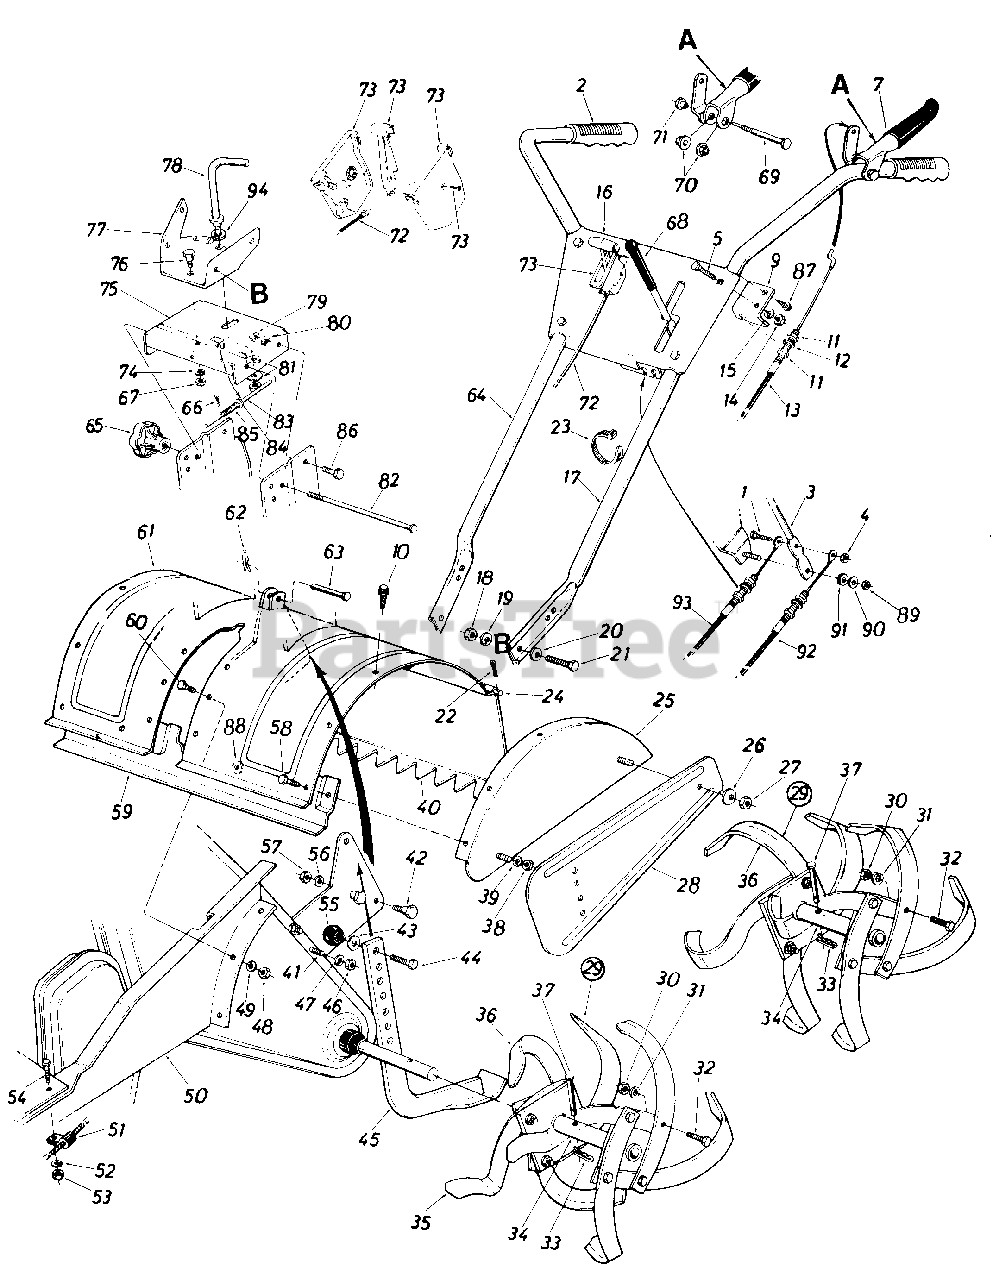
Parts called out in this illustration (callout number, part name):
1	Hex Bolt 1/4-28 x 1.0" Lg.*
2	Grip
3	Clutch Lever
4	Hex Cent. L-Nut 1/4-28 Thd.
5	Carr. Bolt 5/16-18 x 1.75"*
7	Clutch Grip Ass'y.-L.H.
9	Clutch Cable Bracket
10	Hex Wash. S-Tap Scr. 5/16-18 x .62" Lg.
11	Hex Nut 5/16-24 Thd.
12	L-Wash. 5/16" I.D.*
13	Clutch Control Cable
14	Hex Nut 5/16-18 Thd.*
15	L-Wash. 5/16" I.D.*
16	Handle Panel Ass'y.
17	Handle Panel Ass'y.
18	Handle-L.H.
19	Hex Nut 3/8-16 Thd.*
20	Bell-Wash. 3/8" I.D.
21	Hex Bolt 3/8-16 x 1.00" Lg.*
22	Cotter Pin 3132" Dia. x 314"*
23	Cable Tie
24	Tiller Flap Rod
27	Hex Nut 5/16-18 Thd.*
30	Hex Nut 3/8-24 Thd.*
31	L-Wash. 3/8" I.D.*
32	Hex Bolt 3/8-24 x 1.25" Lg.*
33	Hairpin Cotter
38	Hex Nut 5/16-18 Thd.*
39	L-Wash. 5/16" I.D.*
41	Hex Bolt 5/16-18 x 1.0" Lg.*
42	Shld. Bolt 1/2" Dia. x .42611
43	Fl-Wash. 3/8" I.D. x 518" O.D.
44	Hex Bolt 3/8-16 x 314" Lg.*
46	Hex Nut 5/16-18 Thd.*
47	L-Wash. 5/16" I.D.*
48	Hex Nut 5/16-18 Thd.
49	L-Wash. 5/16" I.D.
52	L-Wash. 5/16" I.D.
53	Hex Nut 5/16-18 Thd.
54	Hex Bolt 5/16-18 x 3/4" Lg.
55	Ball Knob 11/4" Dia.
56	L-Wash. 3/8" I.D.
57	Hex Nut 3/8-16 Thd.
58	Hex Bolt 5/16-18 x .75" Lg.
60	Hex Bolt 5/16-18 x .75" Lg.
62	Hairpin Cotter
63	Clevis Pin 3/8" Dia.
64	Handle-R.H.
65	Hand Knob
66	Cotter Pin 1/16" Dia. x .75
67	Hex Cent. L-Nut 3/8-16 Thd.
69	Shoulder Bolt .375" Dia. x 1.37" Lg.
70	Hex Flange Plastic Bearing
71	Shoulder Nut 1/4-20 Thd.
72	Throttle Control Wire
73	Throttle Control Box Ass'y.
74	Bell-Wash. .40" I.D. x 1.13"
79	Hex Cent. L-Nut 3/8-16 Thd.
80	Bell-Wash. .40" I.D. x .88"
81	Bell-Wash. 1/2" I.D. x 1.00"
82	Lock Pin 5/16" Dia. x 8"
83	Lower Sliding Ass'y.
84	Fl-Wash. .291" I.D. x .62"
85	Compression Spring .36" O.D. x 1.00" Lg.
86	Shoulder Bolt 1/2" Dia. x . 170" Lg.
87	Hex Wash. S-Tap Scr. 1/4-20 x.50" Lg.
88	Bell-Wash. 5/16" I.D.
89	Hex Cent. L-Nut 5/16-18 Thd.
90	Fl-Wash. .344" I.D. x .87"
91	Rubber Wash. .33 I.D. x .87"
92	Control Cable
93	Control Cable
94	Fl-Wash. .62" I.D. x 1.57"
